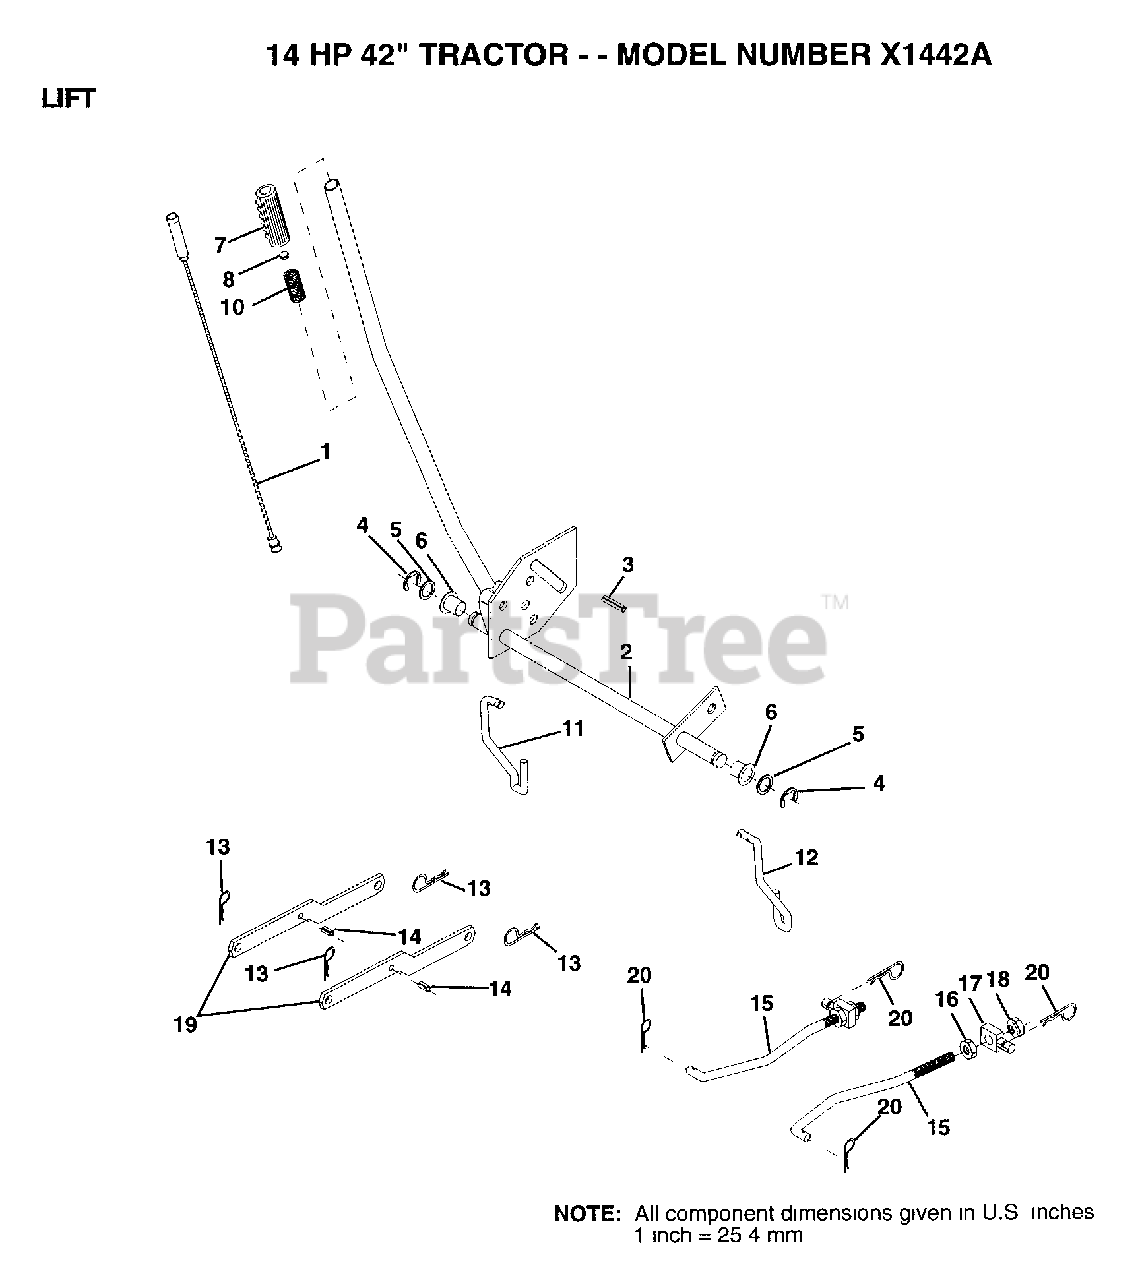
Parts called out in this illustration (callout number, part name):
1	WIRE ASM
3	PIN-GROOVE LT
5	WASHER
6	NYLON BEARING
7	GRIP
11	LINK LIFT LH
12	LIFT LINK RH
14	"PIN,SPRING"
15	LINK.FRONT
16	NUT
17	TRUNION
18	NUT.LK.W/WSH.1/2.
20	RETAINER.SPRING
